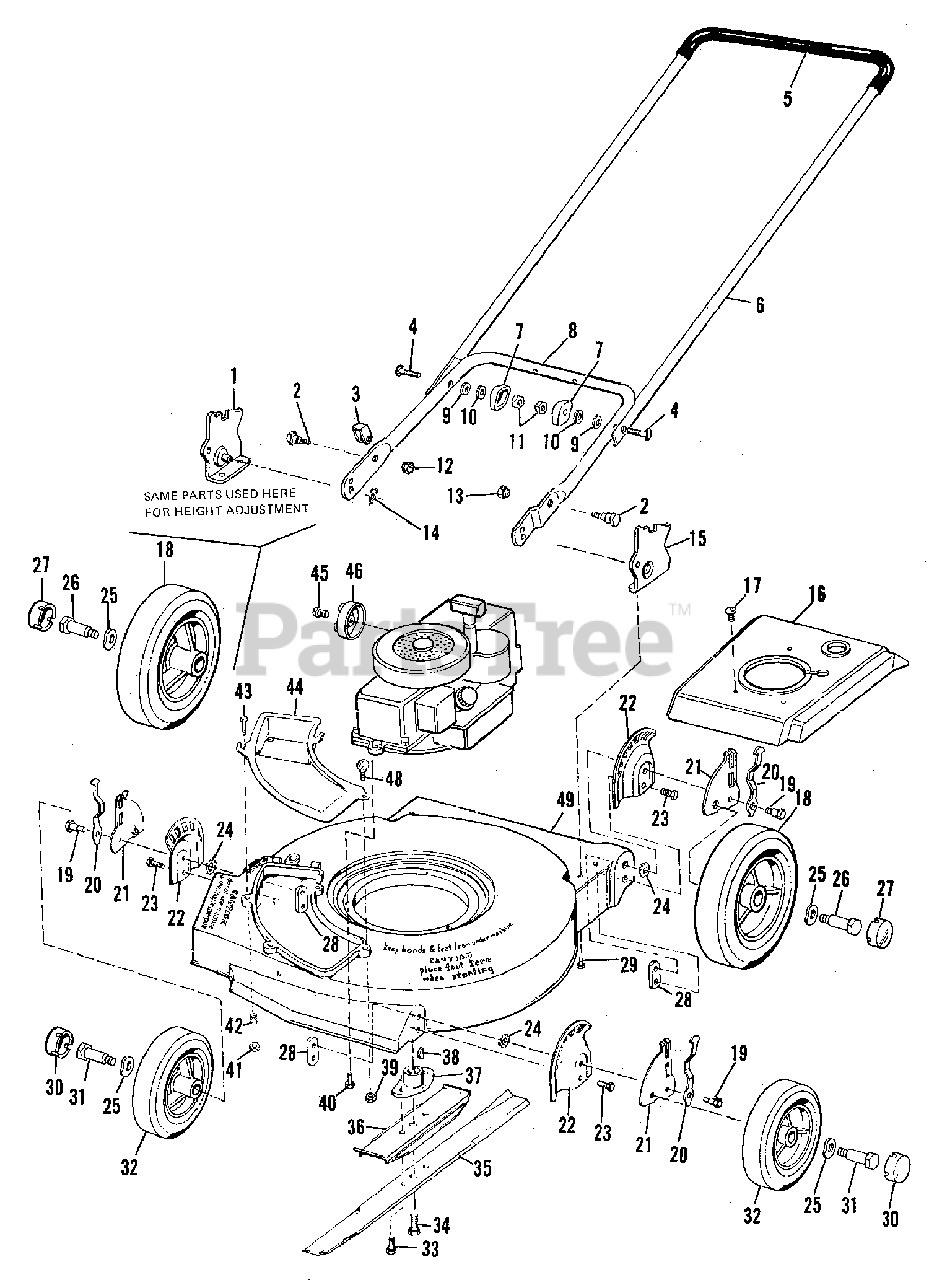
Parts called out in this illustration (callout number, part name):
1	BRACKET, R.H.
2	BOLT, Handle Latch
3	LATCH, Handle
4	BOLT, Curved Head
5	TUBING, Handle
6	HANDLE, Upper
8	HANDLE, Lower
9	WASHER, Flat, 1/4
10	WASHER, Lock, 5/16"
11	NUT, Hex, 5/16-18
12	NUT, Hex, 5/16-18
13	NUT, Handle Latch
14	CLIP, Spring
15	BRACKET, L.H.
17	SCREW, Round head, 8 x 1/2
18	WHEEL & TIRE, 8" (Rear)
19	BOLT, Hex, Shoulder
20	SPRING, Height Adjust
21	ADJUSTER, Height
22	PLATE, Adjusting
23	SCREW, Hex, Cap, 3/8-16 x 5/8
24	WASHER, Lock, 3/8"
25	WASHER, Spring
26	BOLT, Wheel (Rear)
27	CAP, Hub (Rear)
28	NUT, Twin Pilot
29	SCREW, Hex, 1/4-20 x 3/8
30	CAP, Hub (Front)
31	BOLT, Wheel (Front)
32	WHEEL, 6" (Front)
33	SCREW, Hex Cap, 5/16-18 x 1
34	SCREW, Hex Cap, 3/8-24 x 1-1/2
36	STIFFENER, Blade
37	ADAPTER, Blade
38	KEY, Woodruff, #6
39	SPEED NUT, Special
40	BOLT, Engine Mounting, 3/8-16 x 1
41	NUT, Hex, 1/4-20
43	SCREW, Special
44	PLATE, Cover
45	SCREW, Hex, 8 x 1/2
46	BAFFLE, Muffler
47	ENGINE, 3-1/2 HP
48	SCREW, Thumb, 1/4-20 x 5/8
49	HOUSING, 19"
